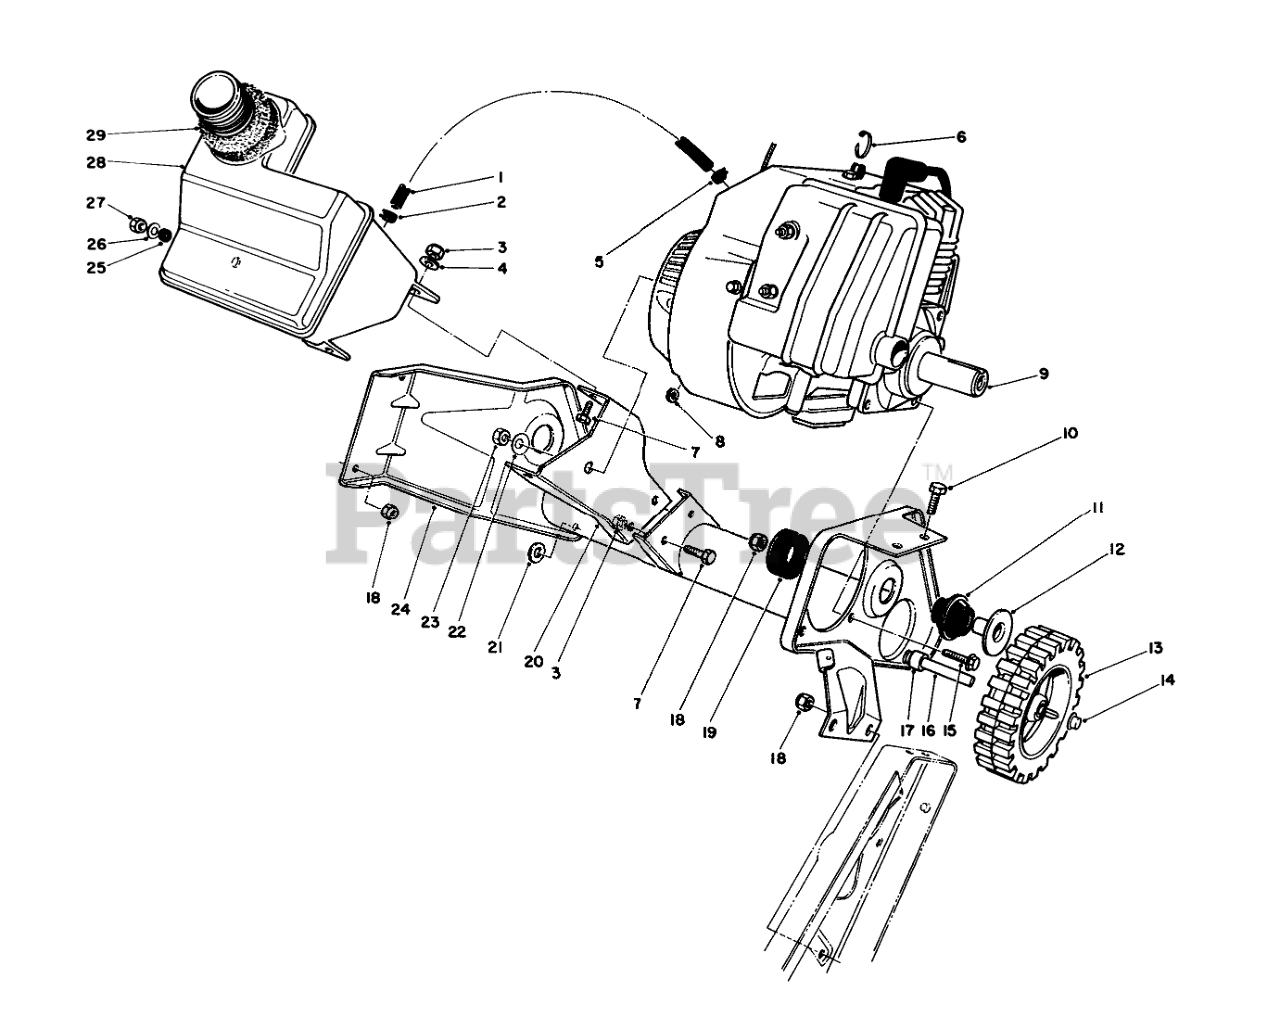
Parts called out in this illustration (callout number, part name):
1	GasLine
2	Clamp
3	NUT-LOCK, NI
4	WASHER-FLAT
5	CLAMP-HOSE
6	TIE-CABLE
7	SCREW-HH
8	SPACER-PLATE, PIVOT
9	Engine ASM
10	SCREW-HH
11	MOUNT-REBOUND
12	SPACER TUBE
13	WHEEL
14	RETAINER-PUSH ON
16	Shaft-Axle
17	WHEEL SPACER
18	NUT-LOCK, NI
19	LOAD MOUNT
20	Support-Recoil
21	WASHER-FLAT
22	WASHER-BELLEVILLE
23	NUT (F/W & PPP)
24	Frame Assembly
25	Grommet
26	WASHER-PLAIN
27	NUT-LOCK, CONE
28	Tank-Fuel
29	SEAL-FOAM
